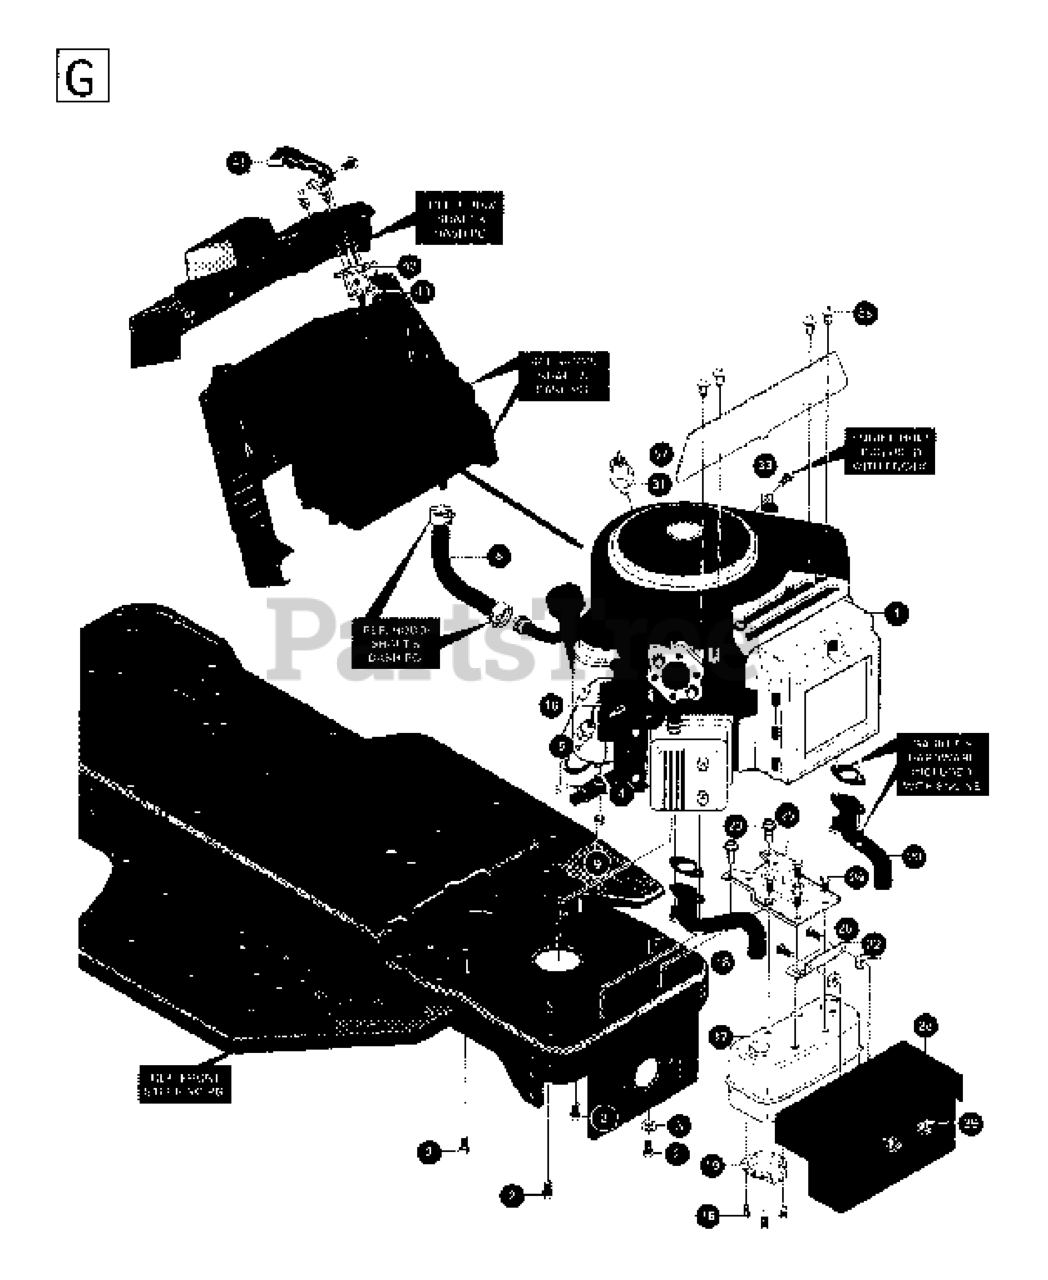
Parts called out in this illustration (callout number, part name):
1	See Engine Manual
2	SCREW
8	FUEL HOSE
16	SCREW
18	PIPE, R.H.
20	PIPE, L.H.
22	BRACKET
23	SCREW
24	SCREW
26	BOLT.CARR.SQNK.5/16-18UNC.X3/4
42	THROTTLE CONTROL
44	NUT
